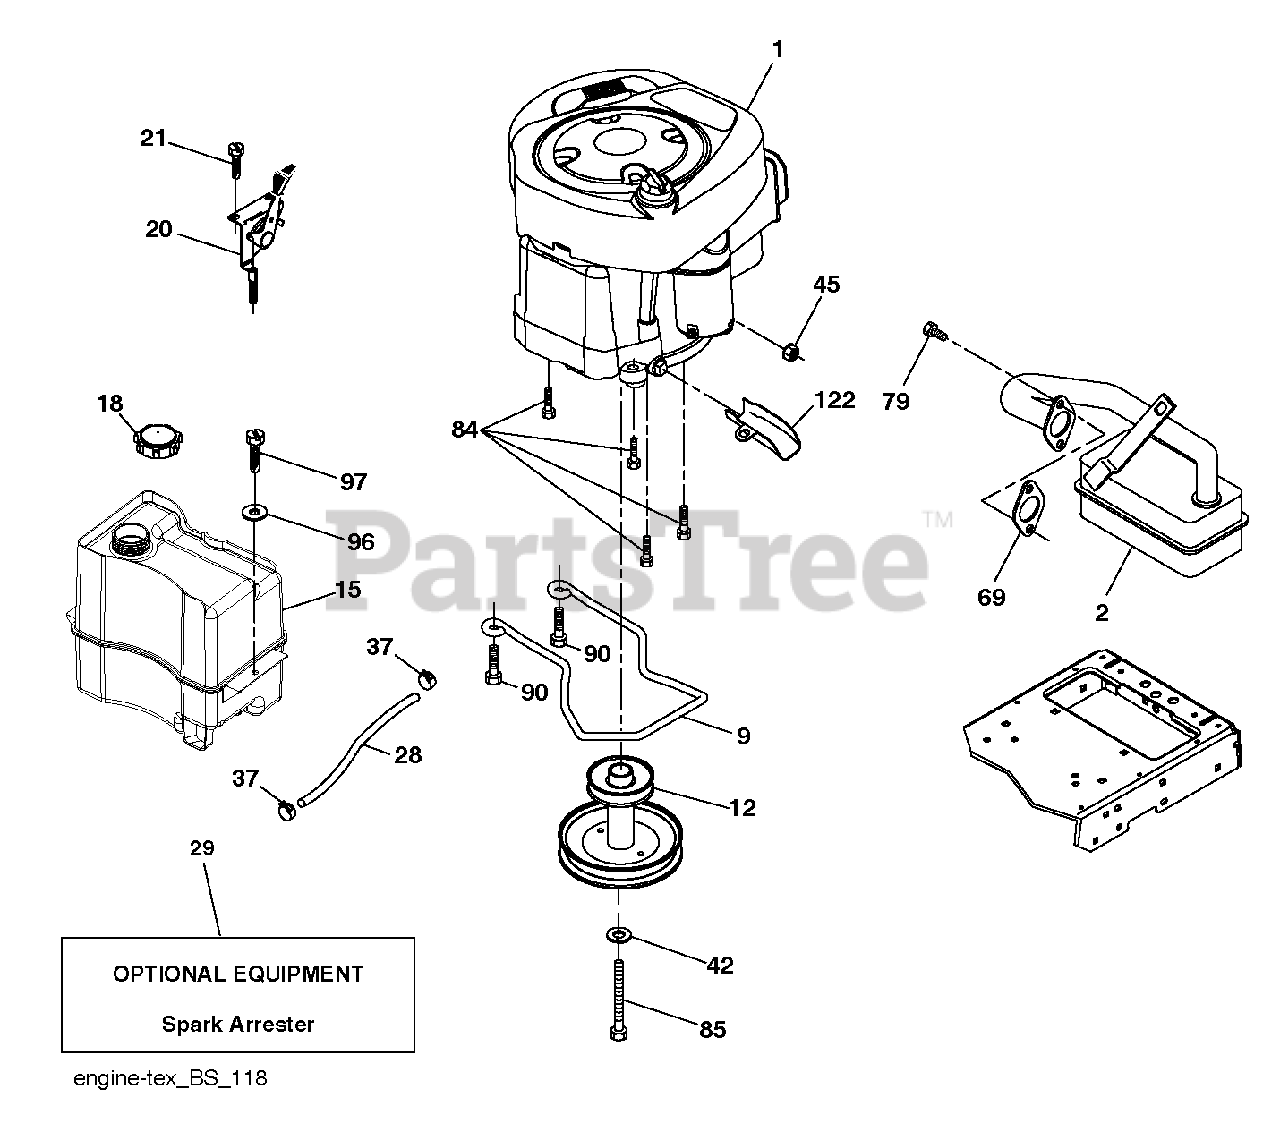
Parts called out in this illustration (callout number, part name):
2	MUFFLER.LT.BRIGGS.14HP.IC/OHV
9	KEEPER.BELT.ENG.3.25"2BOLT.PNT
12	PULLEY.ENG.CL.MECH.SLVR.LT/YT
15	FUEL.TANK.ASM.NON-EPA
18	CAP ASM.FUEL.2.25"FR.
20	THROTTLE.COBRA.21".RSTART.BLK
21	SCREW.#10 X 0.750.BOS
28	LINE.FUEL.20
29	KIT.SPARK ARRESTOR 794945 B&S
37	HOSE CLAMP
42	WASHER 7/16 LOCK
45	NUT
69	REPL BY 532 27 22-93
79	SCREW.SOCKET HD.5/16-1
84	SCREW.3/8-16
85	BOLT.HEX.7/16-20X4.GR5.1.5BLUE
90	SCREW 3/8-16X1
97	SCREW HEXWSHR 1/4-20X3/4
122	EXTENSION DRAIN OIL
